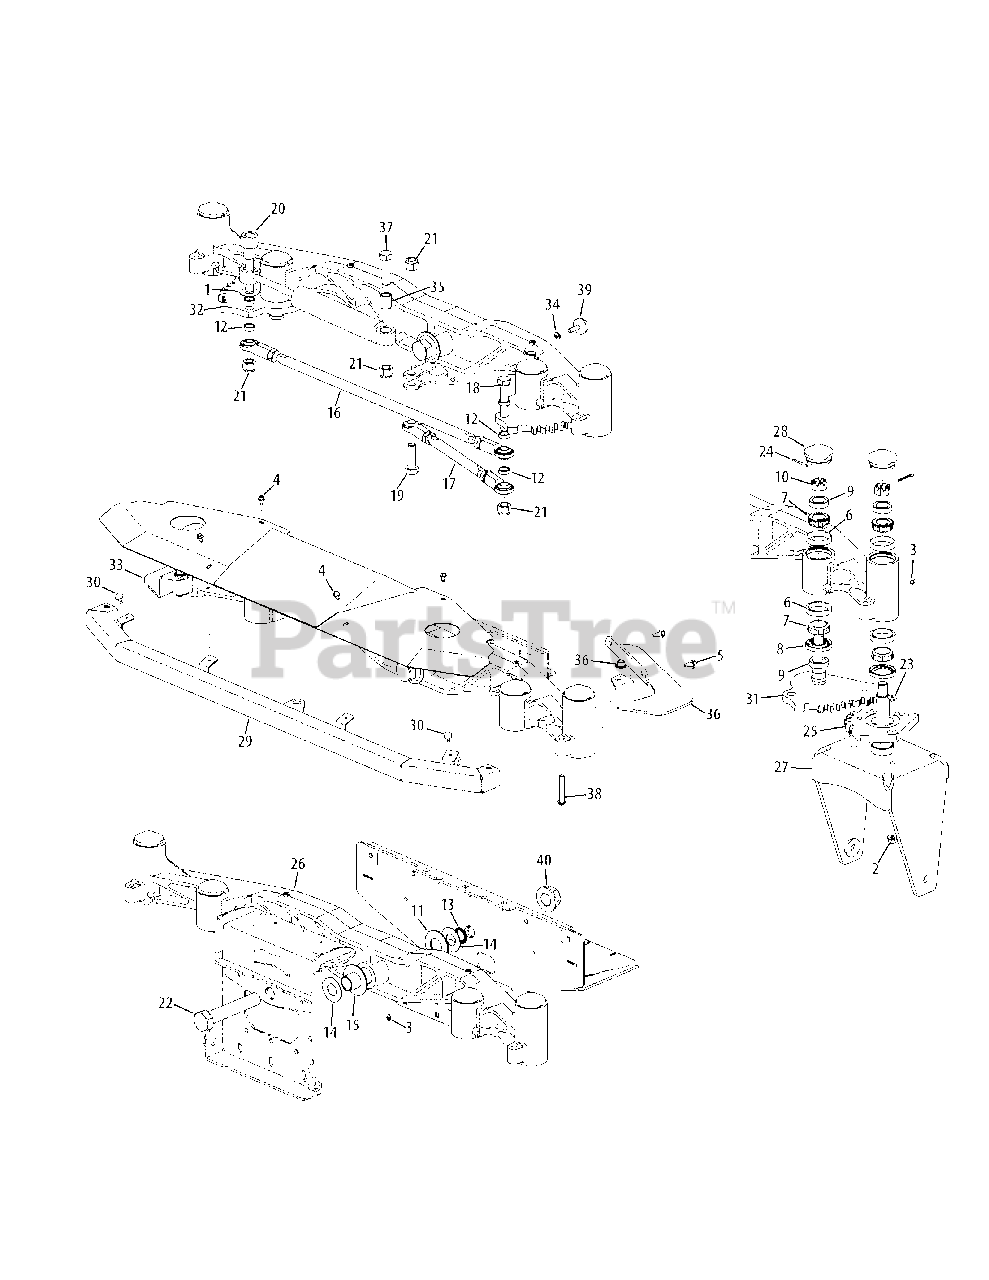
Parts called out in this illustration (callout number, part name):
1	Washer, .655 x 1.5 x .055
2	Flange Counter Lock Nut, 3/8-16
3	Grease Fitting, 1/4-28
4	Hex Flange Screw, 1/4-20 x .500
5	Flange Screw, 5/16-18 x .625
6	Bearing Cup, L44610
7	Cone Bearing, L44643
8	Seal, 14858
9	Seal Ring
10	Slot Nut, 3/4-16
11	Bell Washer, 1.25 x 2.50 x .180
12	Spacer, .635 x .880 x .312
13	Self-Lock External Retainer
14	Washer, 1.00 x 2.00 x .075
15	Spacer, 1.00 x 1.25 x 3.47
16	Tie Rod Assembly, 1/2-20 x 28
17	Tie Rod Assembly, 5/8-18 x 14
18	Hex Screw, 5/8-11 x 4.00
19	Hex Screw, 5/8-11 x 1.75
20	Shoulder Bolt, .872 x 1.030 x 2.88
21	Hex Lock Nut, 5/8-11
22	Hex Screw, 1-14 x 5.5
23	Hex Screw, 3/8-16 x 1.50
24	Cotter Pin, 5/32 x 1.25
25	Yoke Steering Gear
28	Axle Grease Cap
29	Axle Bumper Assembly
30	Rubber Bumper, .62 x .22
31	LH Steering Gear Assembly
32	RH Steering Gear Assembly
35	Spacer, .635 x .875 x 1.031
38	Screw, 3/8-16 x 2.25
39	Adjustable Skid Shoe
40	Flange Top Lock Nut, 1.0-14
